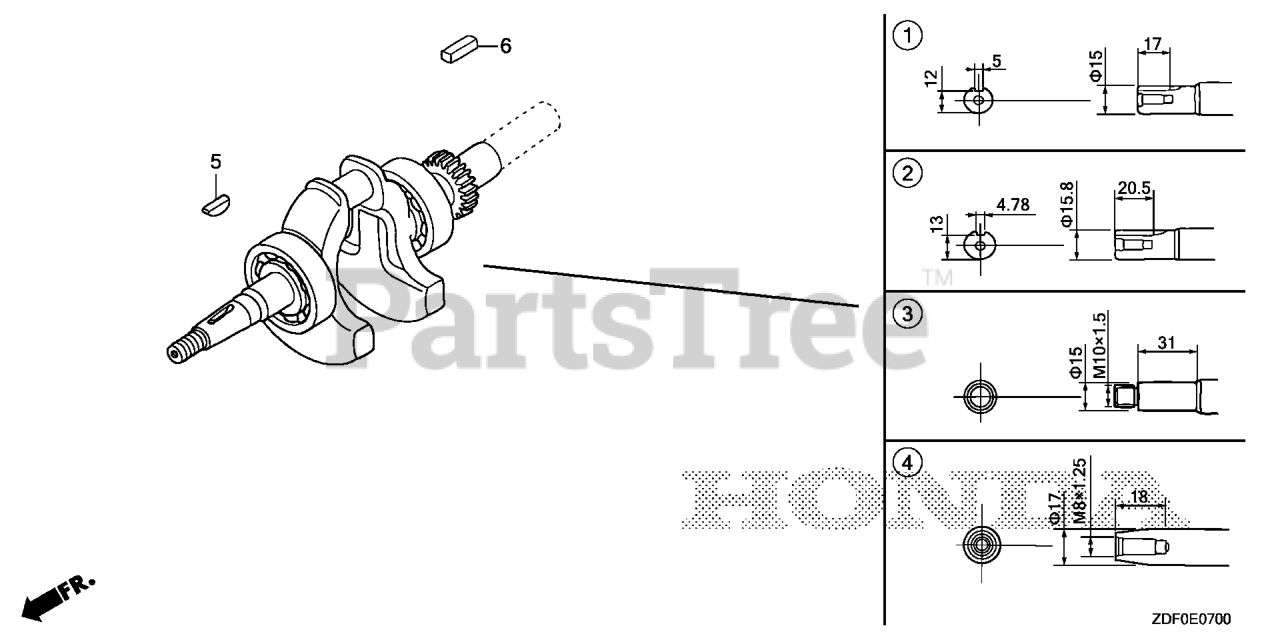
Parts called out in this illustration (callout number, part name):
1	CRANKSHAFT
5	KEY, SPECIAL
6	KEY (5MM)
